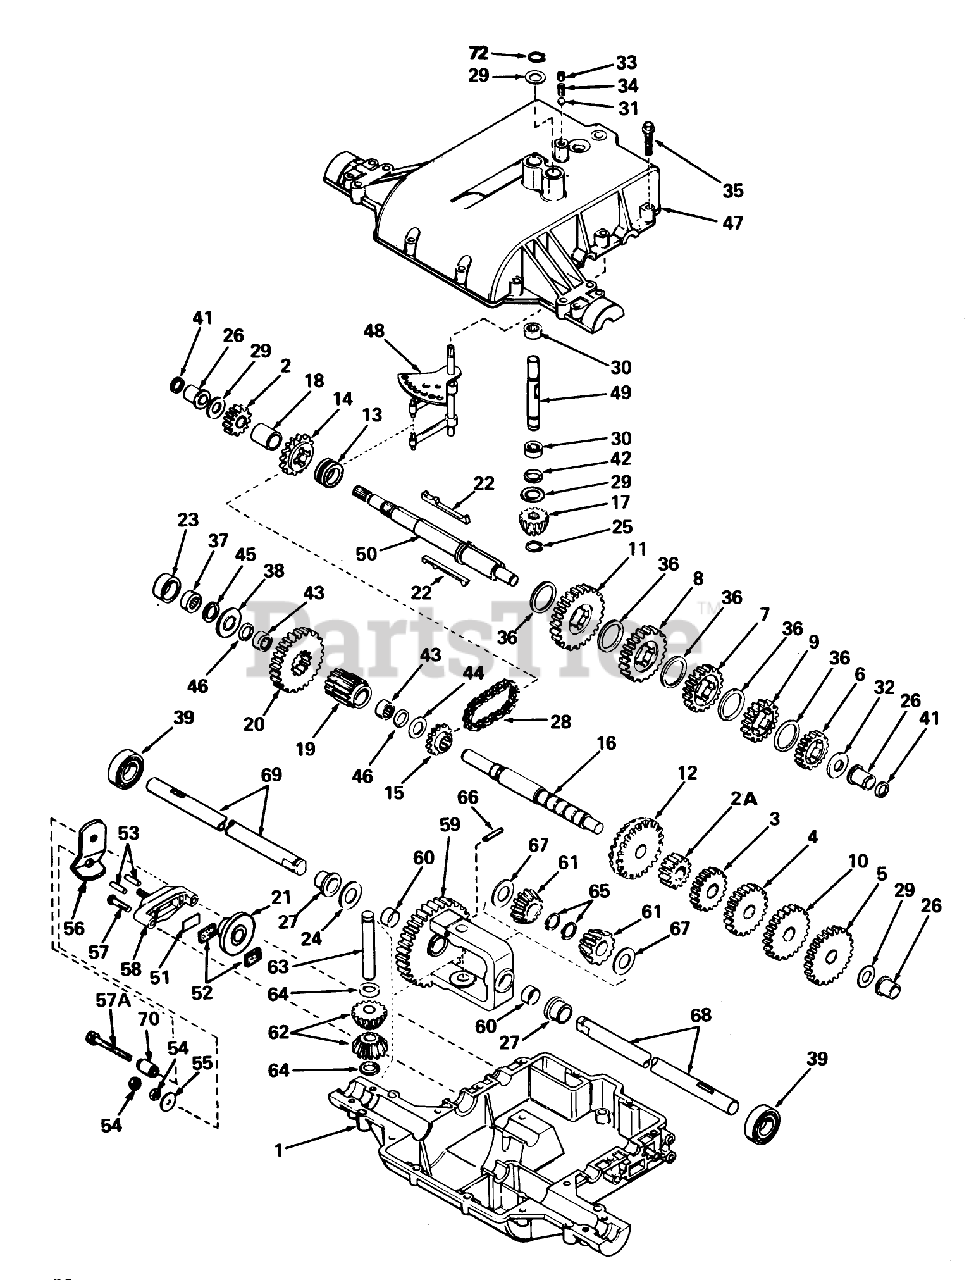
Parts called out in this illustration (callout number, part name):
1	Case-Transaxle
2	Gear-Spur 15 Teeth
2A	Gear-Spur, 12 Teeth
3	Gear-Spur, 20 Teeth
4	Gear-Spur, 25 Teeth
5	Gear-Spur (30 teeth)
6	Gear-Spur 20 teeth
7	Gear-Spur, 25 Teeth
8	Gear-Spur, 30 Teeth
9	Gear-Spur (22 teeth)
10	Gear-Spur (28 teeth)
11	Gear, Spur (37 teeth)
12	Gear, Bevel (42 teeth)
13	Collar-Shift
14	Sprocket-18 Teeth
15	Sprocket-9 Teeth
16	Shaft-Counter
17	Bevel Pinion-Input
18	Spacer
19	Pinion-Output
20	Gear-Output
23	Spacer
24	Washer
25	Ring-Retainer
26	Bushing, Flanged
27	Bushing, Flanged
28	Chain-Roller #41
29	Washer
30	Bearing-Needle
31	Ball-Steel
32	Washer
33	Screw-Set
34	Spring
35	Ring Set (.020 O S)
36	Washer
37	Bearing-Needle
38	Washer-Flat
39	Bearing-Ball
41	Ring-Square Cut
42	O Ring
43	Bearing-Needle
44	Washer-Flat
45	Ring-Square Cut
46	Ring-Square Cut
47	Cover-Transaxle
48	Rod Fork Assembly
49	Shaft-Input
50	Shaft, Brake
51	Brake Pad Plate
52	Brake Pad
53	Dowel Pin
54	Locknut
55	Washer
56	Lever-Brake
57	Ring Set (.020 O S)
57A	Screw-Hex. Flange
58	Holder-Brake Pad
59	Gear Assy., Differential (Incl. 2 of No. 60)
60	Bushing
61	Bevel Gear
62	Gear Pinion
63	Drive Pin
64	Thrust Washer
65	Ring-Snap
66	Pin-Roll
67	Washer
68	Axle (14 7/8" long)
69	Axle (13" long)
70	Spacer
72	Ring-Snap
